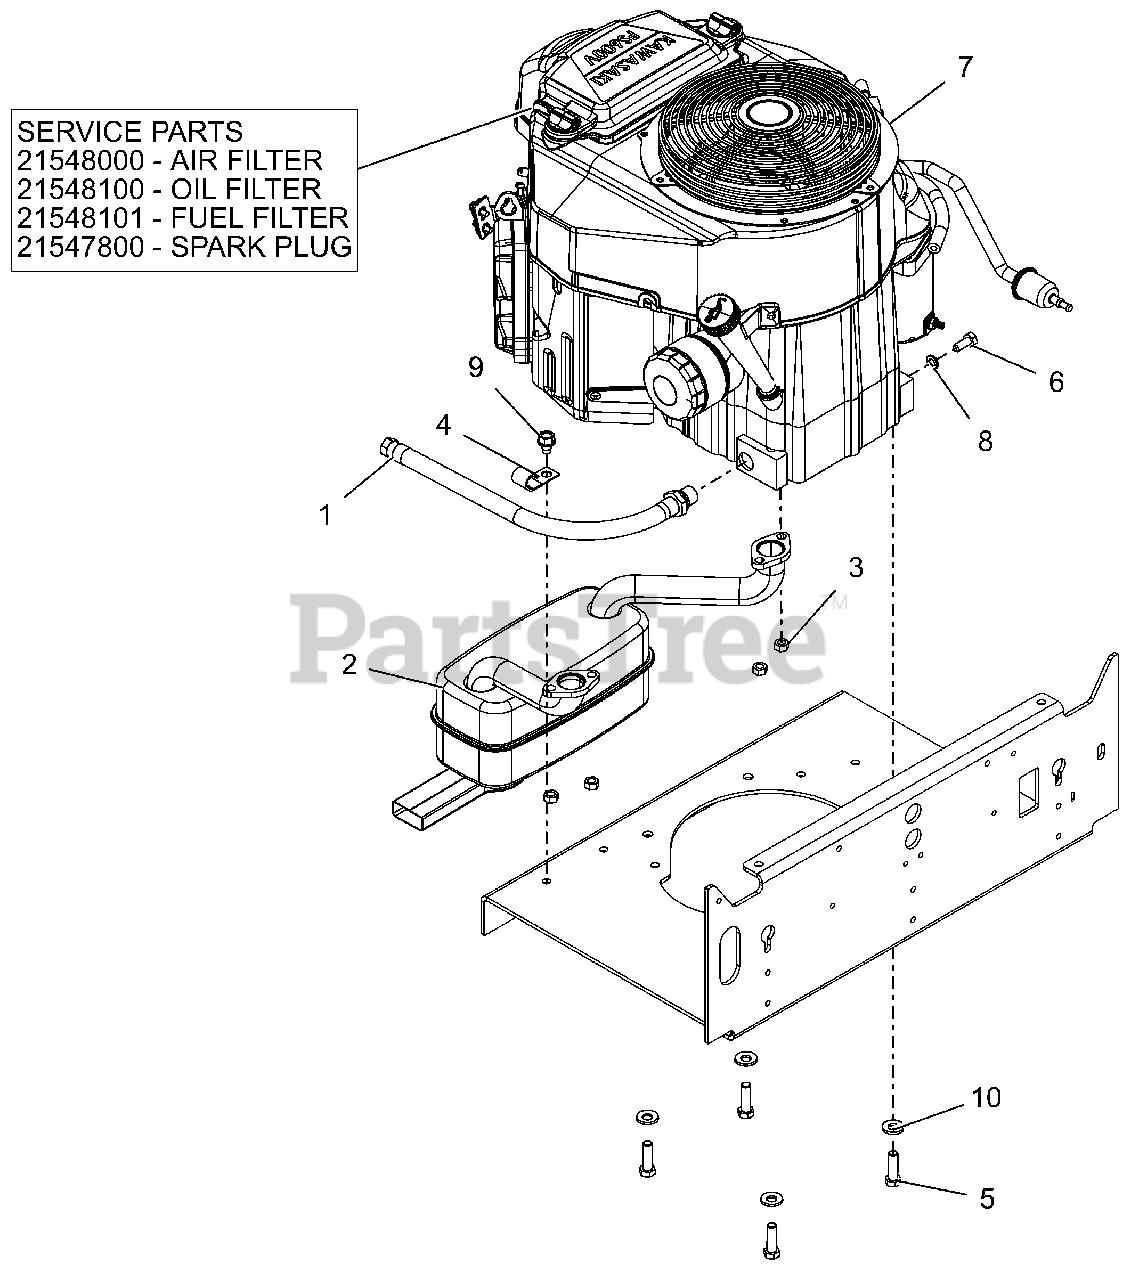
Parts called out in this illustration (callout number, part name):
1	HOSE, OIL DRAIN
2	MUFFLER, KAW FS691/730
3	NUT-LK-TOP M8-1.25 YWZC
5	BLT-HEX.38-16X1.25 G5YZ NYTORQ
6	@BLT-HEX M8-1.25X20 YWZC
7	ENGINE, KAWASAKI FS691
7	AIR FILTER, KAWASAKI FR
7	OIL FILTER, KAWASAKI FR
7	FUEL FILTER-KAWASAKI FR
7	SPARK PLUG, KAWASAKI FR
8	@WSHR-LK .31X.078 REG YWZC
9	@SCR-TAP .38-16X.50 HWH TR YWZ
10	WASHER, 3/8" SPRING DISC
